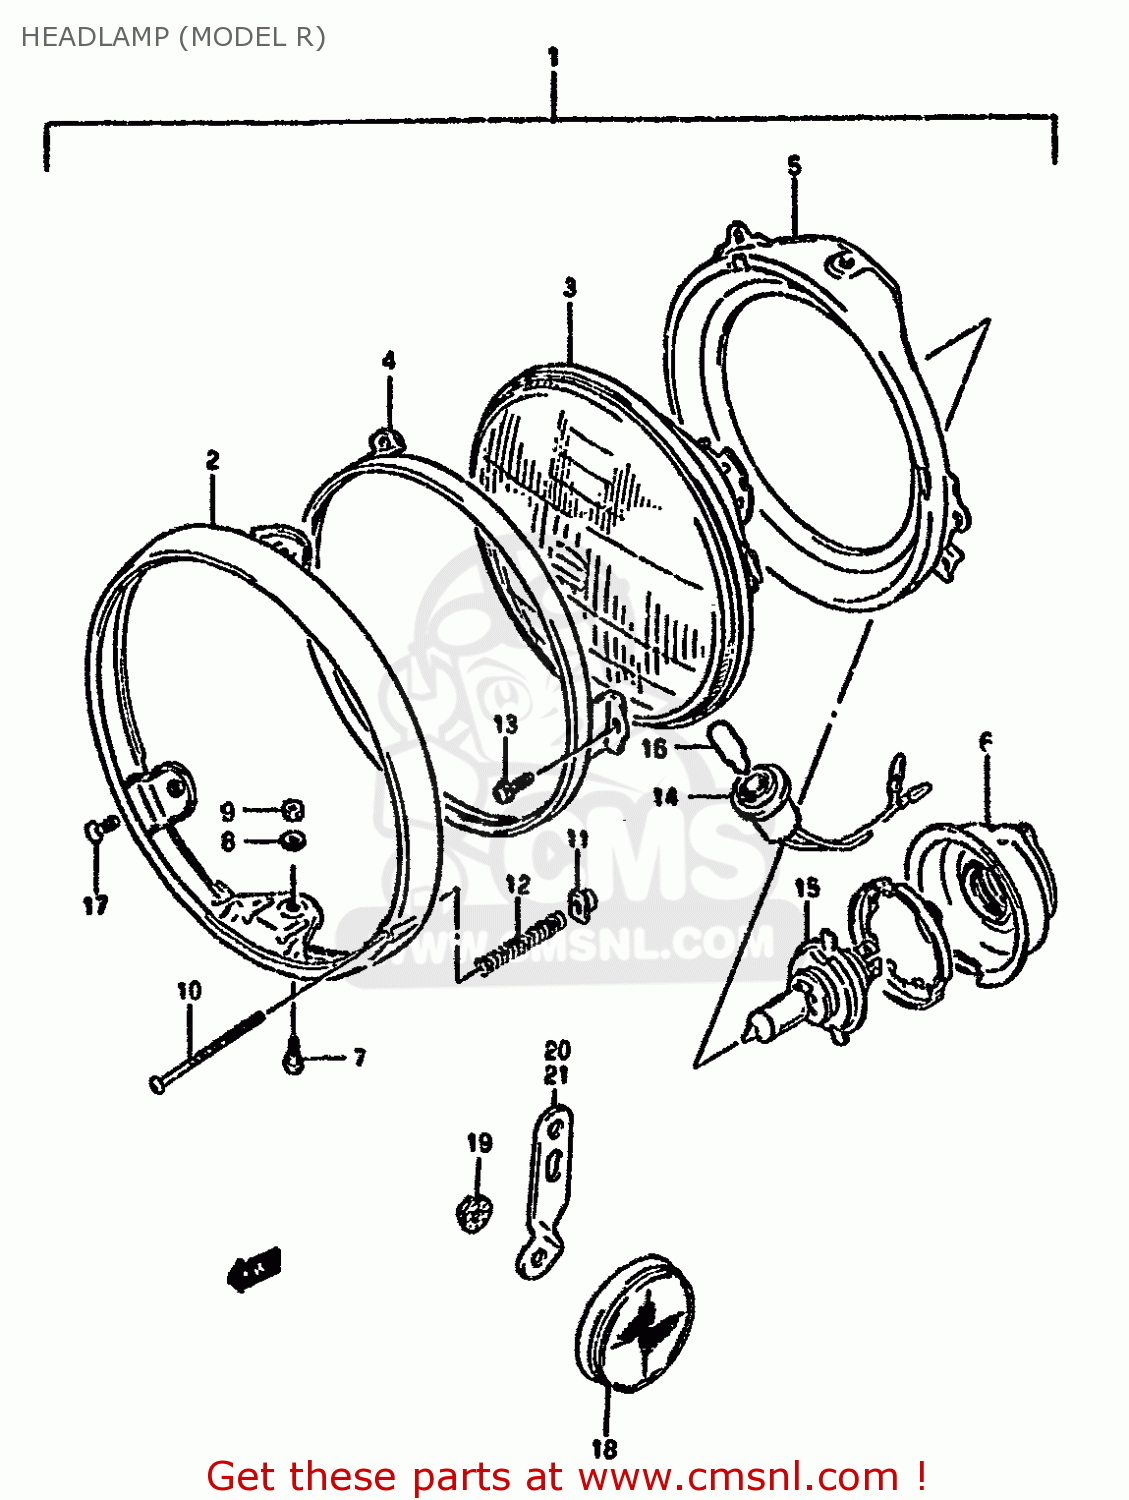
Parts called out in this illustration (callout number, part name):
1	HEADLAMP ASSY
2	RIM,HEADLAMP
3	LAMP UNIT
4	RING
5	RING
6	COVER,SOCKET
7	H/LAMP LENS UNIT FITING SCRE
8	WASHER,LOCK
9	NUT
10	SCREW,HEADLAMP ADJUST
11	NUT
12	SPRING,ADJUSTING
13	SCREW
14	SOCKET,PARKING LAMP
15	BULB(12V60/55W,H4)
16	BULB(12V4W)
17	SCREW
18	REFLECTOR,REFLEX FR
19	NUT
20	BRACKET,FRONT SIDE REFLECTOR
21	BRACKET,FRONT SIDE REFLECTOR
25	BRACKET,FRONT SIDE REFLECTOR
